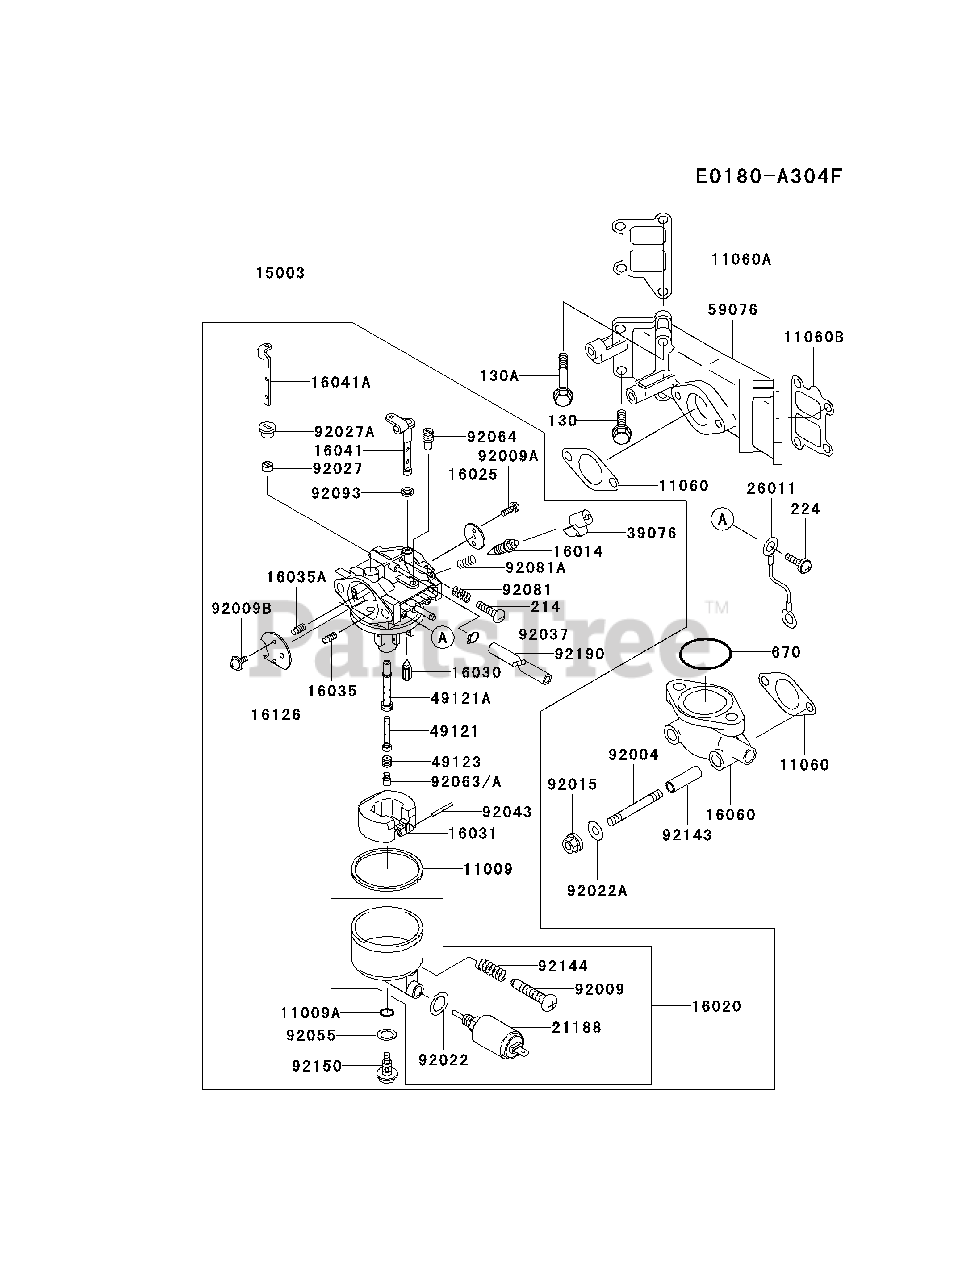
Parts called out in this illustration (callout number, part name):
130	BOLT-FLANGED,6X16
130A	BOLT-FLANGED,6X40
214	SCREW-PAN+-,4X14
224	SCREW-PAN-WP-CROS,5X8
670	O RING,32MM
